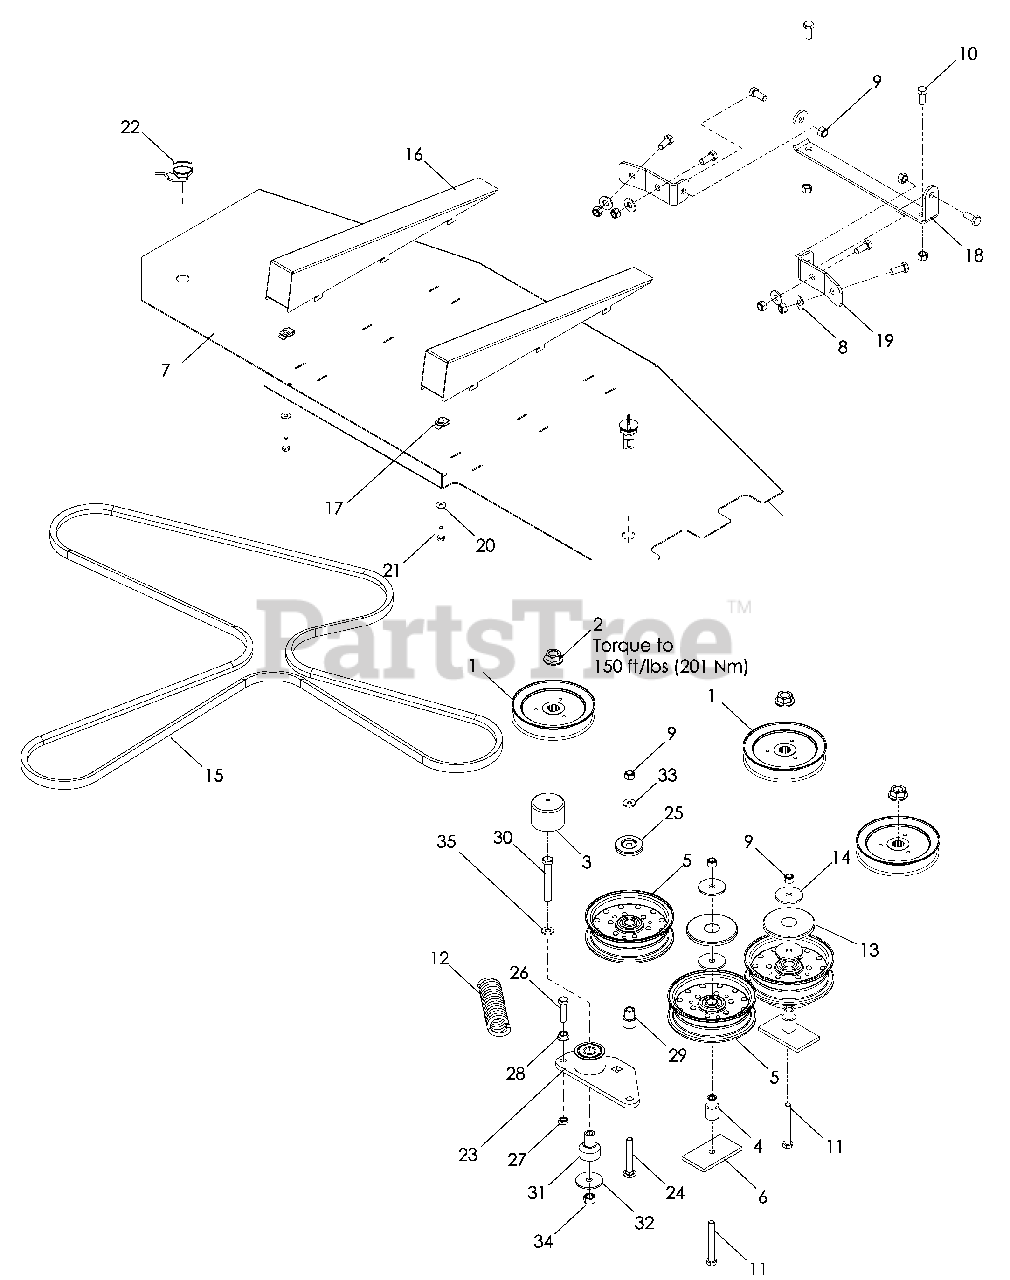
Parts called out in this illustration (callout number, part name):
2	NUT ¾-16 FLANGE
3	CAP, VINYL
4	BUSHING, IDLER
5	PULLEY, IDLER
6	PAD, PAINTED
7	COVER, BELT, 48
8	WASHER 3/8 FLAT
9	NUT 3/8-16 HEX NYLOC
10	HCS 3/8-16 x 7/8
11	HCS 3/8-16 x 3
13	DUST CAP, TOP
14	WASHER, 3/8 SPECIAL
15	BELT, DECK
17	RETAINER ¼-20 "U" TYPE
18	HINGE, BIN
19	BASE, HINGE
20	WASHER, ¼ FLAT SAE
21	HCS ¼-20 x ¾
22	LATCH, SHORT WING
23	ARM, IDLER, W/BEARINGS
24	RHSNB 3/8-16 x 2¾
25	SHIELD, DUST
26	HCS 3/8-16 x 1½ GR 8
27	NUT 3/8-16 HEX JAM
28	NUT 3/8-16 HEX WHIZLK
29	BUSHING, IDLER
30	HCS ½-13 x 3¼
31	PIVOT, BEARING
32	WASHER, SUPPORT
33	WASHER, THICK 3/8
34	NUT ½ HEX NYLOC
35	WASHER, BELLEVILLE ½
